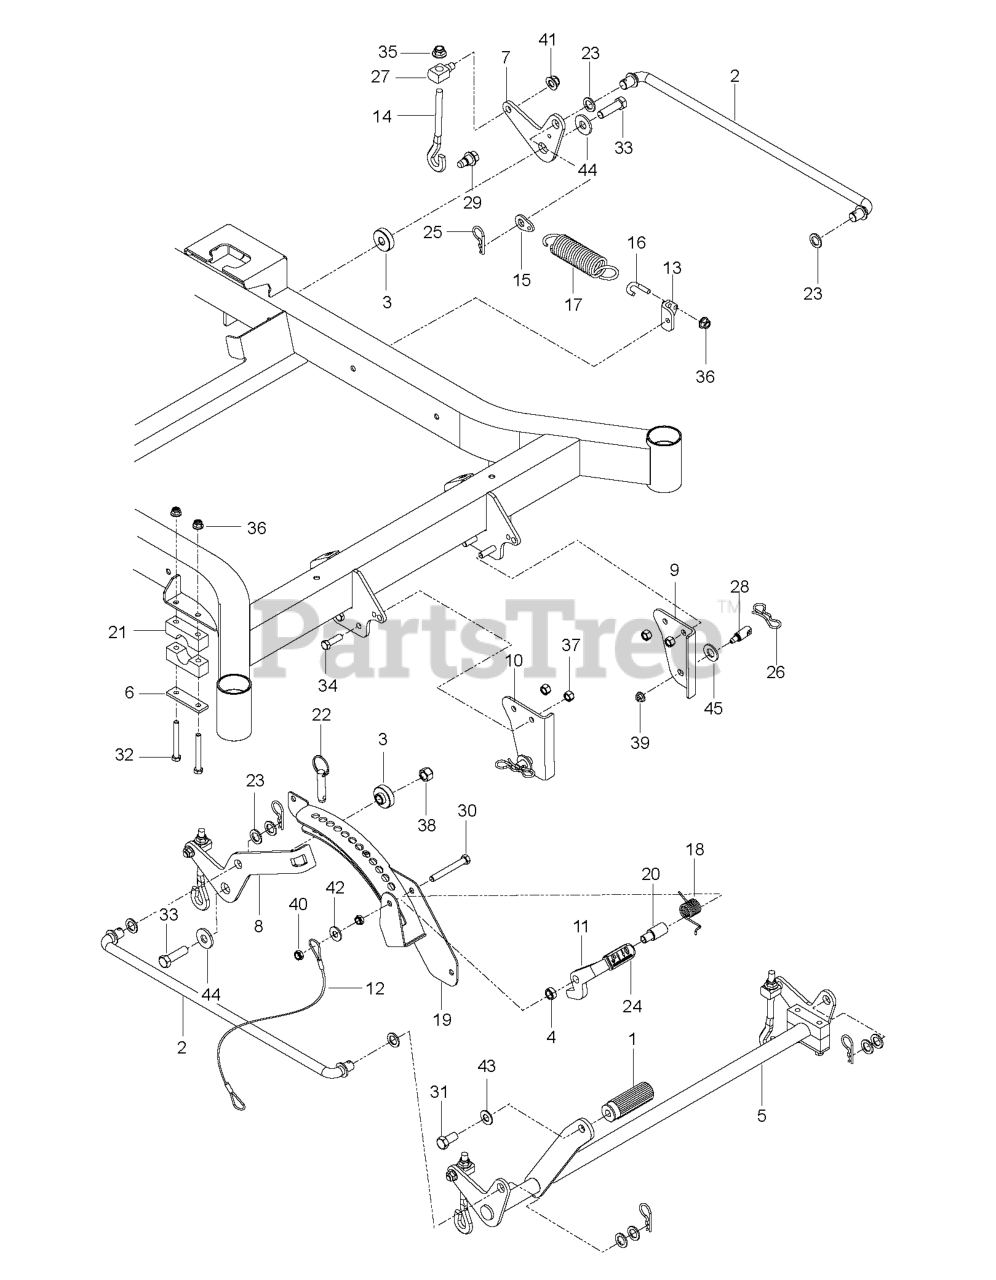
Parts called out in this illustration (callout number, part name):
1	PEDAL, DECK HEIGHT
2	CROSS LINK
3	SPACER.IDLER.METAL.POWDER
4	SPACER, .3
5	LIFT.PNT.MZ.DECK.WELD.E-DIP
6	REINFORCEMENT.PLATEX431
7	BELLCRANK, RR, LIFT
8	BELLCRANK, RR, RT
9	BRACKET.PNT.SUSP.CHAS.FR.LH.OR
10	BRACKET.PNT.SUSP.CHAS.FR.RH.OR
11	LATCH, TRANSPORT
13	MOUNT, SPRING
14	LINK.ADJUSTABLE
15	TAB, SPRING
16	J-BOLT
18	SPRING, TORSION
19	HEIGHT, ADJUST, DECK
20	PIVOT, LATCH, TRANSPORT
21	PILLOW BLOCK
22	PIN, 1/2 X 1 1/2, DETENT RING
23	BUSHING
24	GRIP, TRANSPORT-RELEASE
25	PIN, COTTER 1 3/4
26	PIN.COTTER.7/16.BOW TI.
28	STUD.FASTNER.W/ANTI-ROTATE
29	BOLT.SHOULDER
30	BOLT.HEX.FIN.3/8-16 X 3.GR5
31	HHCS 1/2-13 X 1
32	HCS 5/16C X 2-3/4
33	HCS 1/2-13 X 1 3/4 GR 8
34	HCS 3/8-16X1.GRD.5.ZD
35	NUT.FLANGE.LOCK
36	5/16-18 NYLOC FLANGE NUT
37	NUT 3/8-16 NYLOC
38	NUT 1/2-13 HEX NYLOC ZD
39	NUT LOCK HEX FLANGE 5/16-18
40	NUT HEX 3/8-16 NYLON, THIN
41	NUT LOCK FLG 3/8-16 UNC
42	RP WASHER 3/8 FLAT
43	WASHER, 7/16 DISC SPRING
44	WASH USS FLAT 1/2
45	WASHER.CLEAR.ZINC
